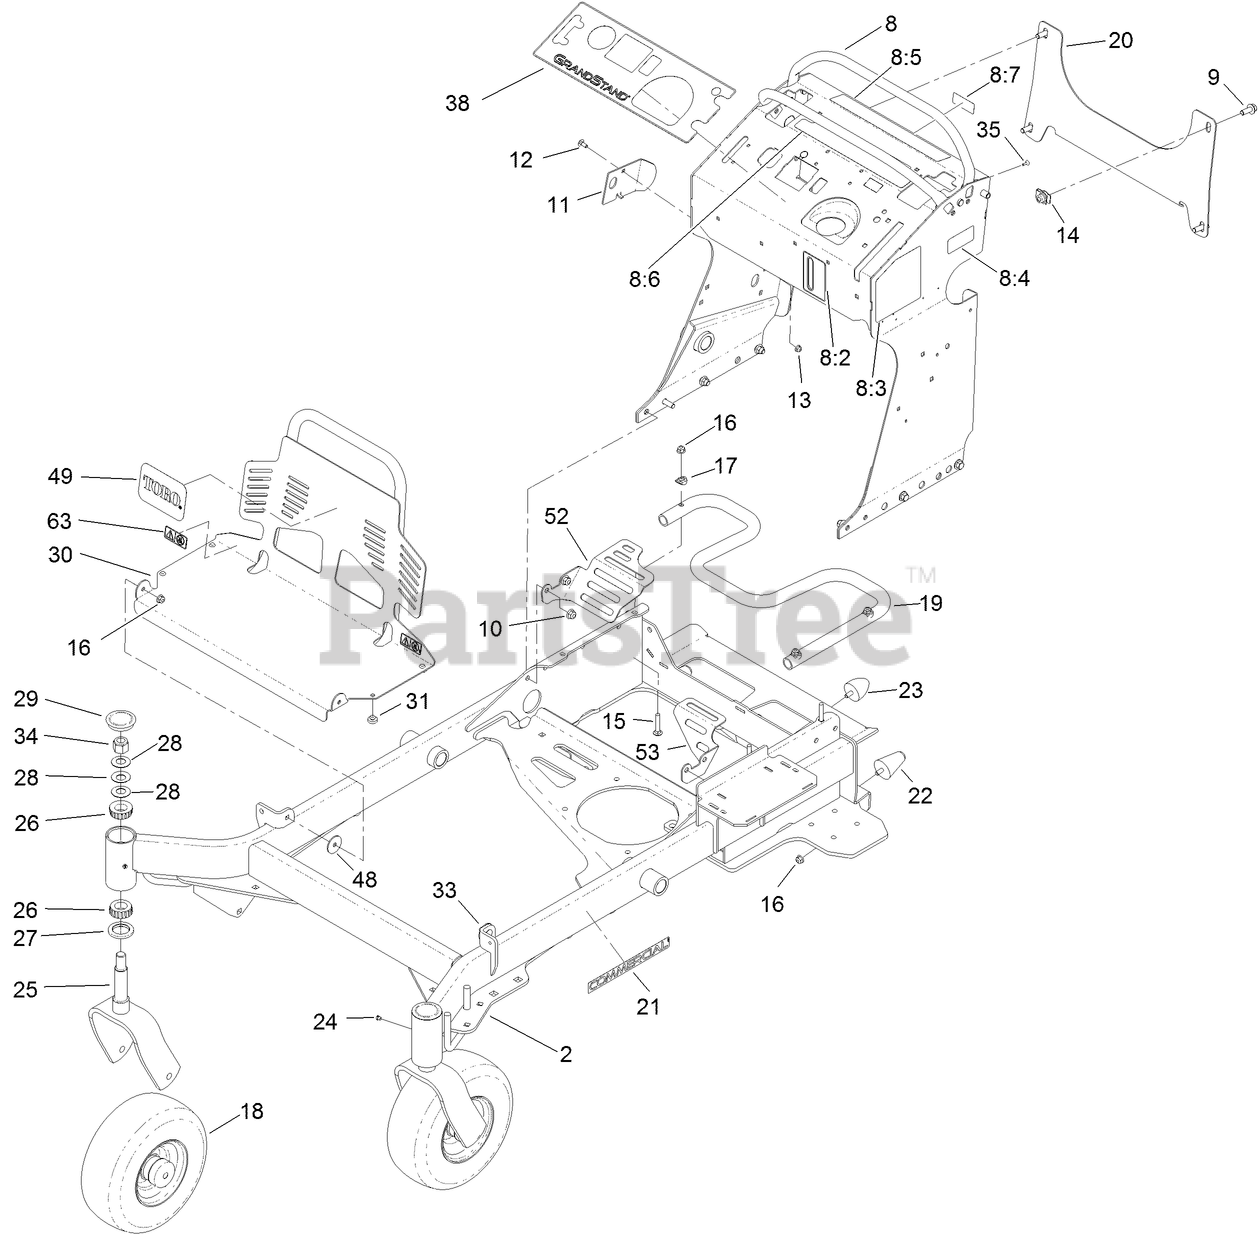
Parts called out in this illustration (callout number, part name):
8	TOWER DECAL ASM
8:2	DECAL-LEVEL, OIL
8:3	DECAL-SERVICE AID
8:4	DECAL-FILL, FUEL
8:5	OBS DECAL-CAUTION
8:6	DECAL-CONTROLS
8:7	DECAL-FUSE
9	SCREW-HHF
10	NUT-HF, NI
11	PLATE-STRIKER
12	SCREW-CARR
13	NUT-HF
14	Nut-Tinnerman
15	SCREW-CARR
16	NUT-HF, NI
17	WASHER
18	WHEEL/TIRE AND BEARING ASM
19	TUBE-MOUNT, FUEL TANK
20	BRACKET-CROSS
21	DECAL-COMMERCIAL
22	BUMPER-RUBBER
23	BUMPER-RUBBER
24	FORK-CASTER
26	BEARING-ROLLER, TAPERED
27	SEAL-GREASE
28	WASHER-BELLVILLE
29	CAP-GREASE
30	GUARD-ENGINE
31	BUMPER
33	BOLT-CARR
34	NUT-LOCK, NI
35	RIVET-POP
38	DECAL-PANEL, CONTROL
48	WASHER-NYLON
52	GUARD-FAN, RH
53	GUARD-FAN, LH
63	DECAL-WARNING, NO RIDERS
